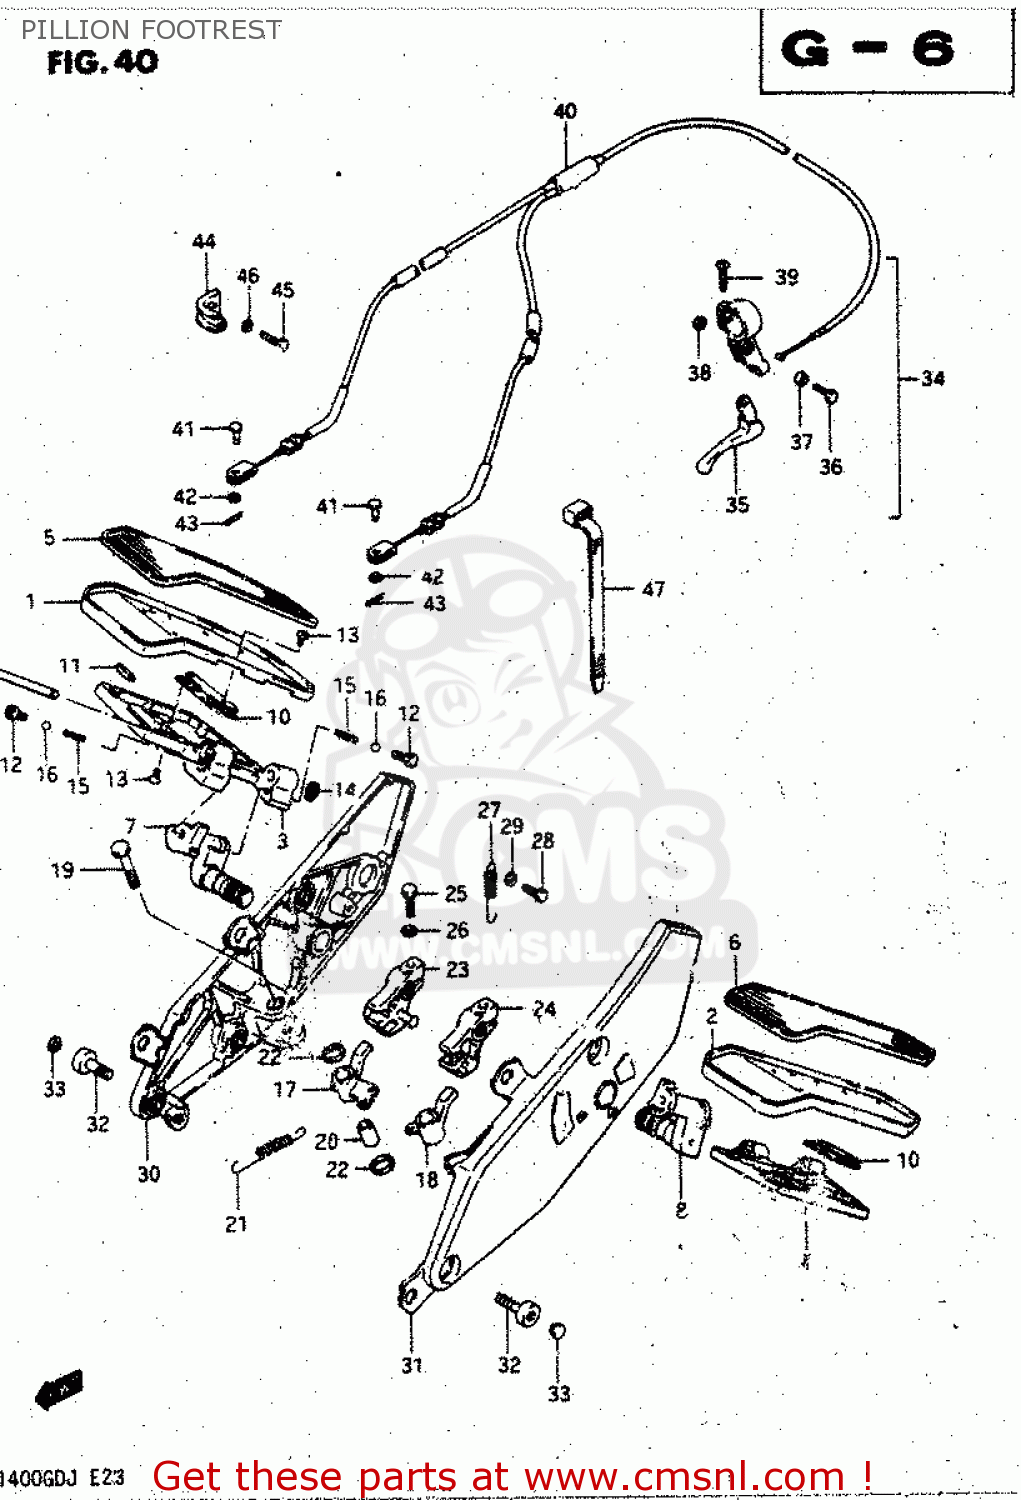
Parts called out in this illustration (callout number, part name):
1	BOARD,PILLION FOOT,UPPER
2	BOARD,PILLION FOOT,UPPER
3	BOARD,PILLION FOOT,LOWER
4	BOARD,PILLION FOOT,LOWER
5	RUBBER,PILLION FOOTBOARD
6	RUBBER,PILLION FOOTBOARD
7	BAR,PILLION FOOTBOARD
8	BAR,PILLION FOOTBOARD
9	PIN,PILLION FOOTREST
10	CUSHION,PILLION BOARD
11	CUSHION,FOOTBOARD
12	BOLT,PILLION BOARD SPRING
13	SCREW(5X10)
14	CIRCLIP,10MM
15	SPRING
16	BALL
17	LEVER COMP,FOOTBOARD
18	LEVER COMP,FOOTBOARD
19	BOLT(10X38)
20	SPACER,PILLION BOARD,LEFT
21	SPRING
22	SHIM
23	CAM,PILLION FOOT BOARD
24	CAM COMP,PILLION FOOT
25	BOLT
26	LOCK WASHER
27	SPRING
28	BOLT
29	NUT 6MM
30	BRACKET,MUFFLER,RIGHT
31	BRACKET,MUFFLER,LEFT
32	BOLT 10X30
33	CAP
34	LEVER ASSEMBLY,PILLION FOOT
35	LEVER
36	BOLT
37	SPACER,DECOMPRESSION LEVER
38	NUT 8MM
39	SCREW
40	CABLE,PILLION FOOTREST
41	PIN(L:13)
42	WASHER
43	PIN
44	BRACKET, FOOTREST
45	BOLT
46	WASHER,LOCK
47	CLAMP(L:165)
